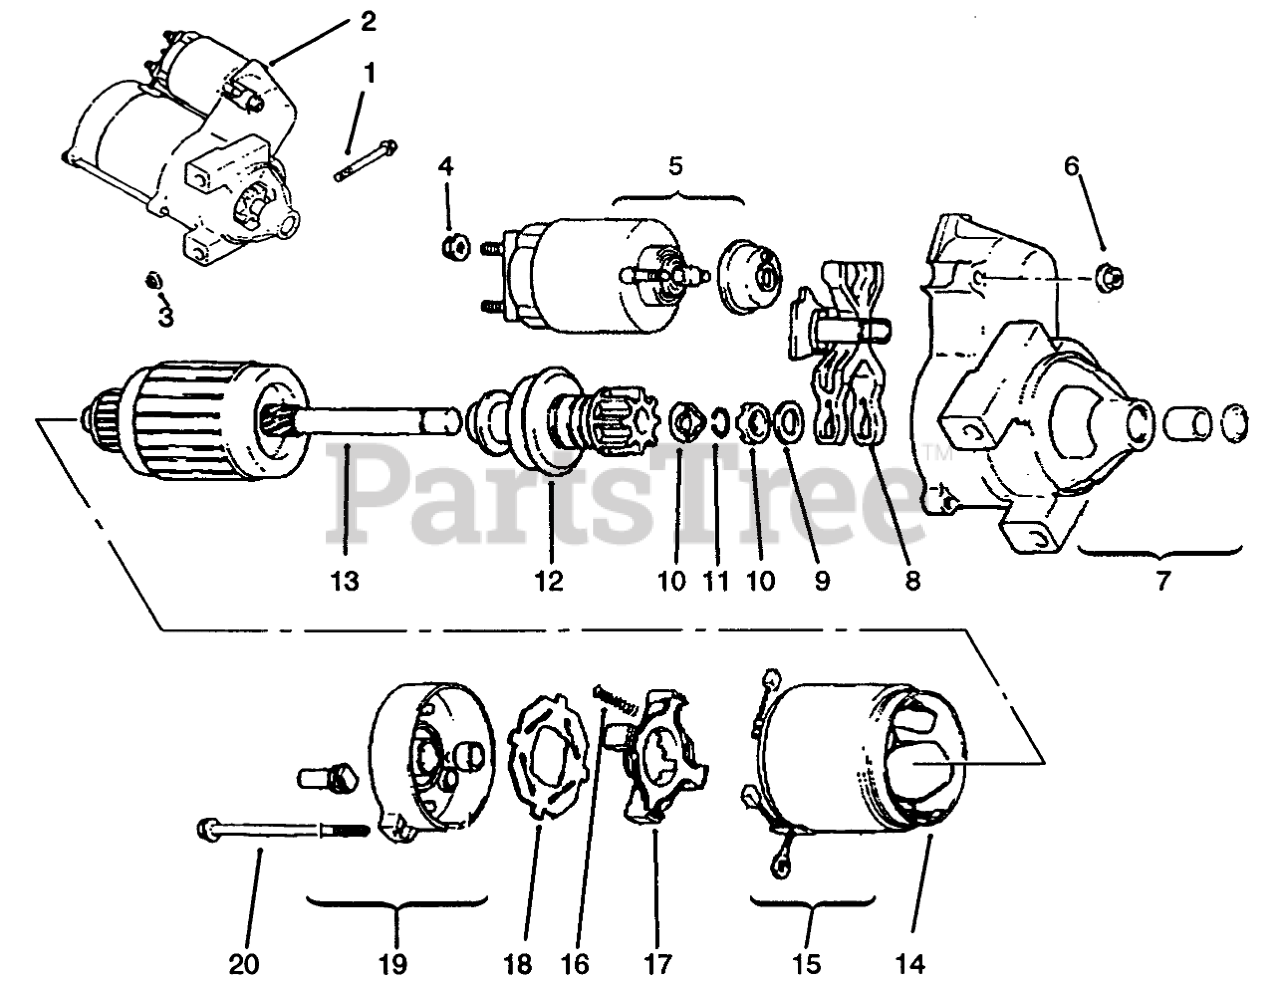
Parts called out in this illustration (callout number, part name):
1	Screw M8x1.25x80 (Only On: 72103, 72083)
2	Starter INC 4-20 (Only On: 72103, 72083)
3	Nut M8x1.25 (Only On: 72103, 72083)
4	Nut-Starter (Only On: 72103, 72083)
5	Solenoid (Only On: 72103, 72083)
6	Nut Starter (Only On: 72103, 72083)
7	Cap-Drive End (Only On: 72103, 72083)
8	Lever Starter Drive (Only On: 72103, 72083)
9	Washer-Thrust (Only On: 72103, 72083)
10	Nut-Stop Collar (Only On: 72103, 72083)
11	Ring-Retainer (Only On: 72103, 72083)
12	Drive-Pinion (Only On: 72103, 72083)
13	Armature-Starter (Only On: 72103, 72083)
14	Frame (Only On: 72103, 72083)
15	Kit-Brush INC 16 (Only On: 72103, 72083)
16	Spring-Brush (Only On: 72103, 72083)
17	Holder-Brush (Only On: 72103, 72083)
18	Insulator (Only On: 72103, 72083)
19	Cap-Commutator End (Only On: 72103, 72083)
20	Bolt (Only On: 72103, 72083)
